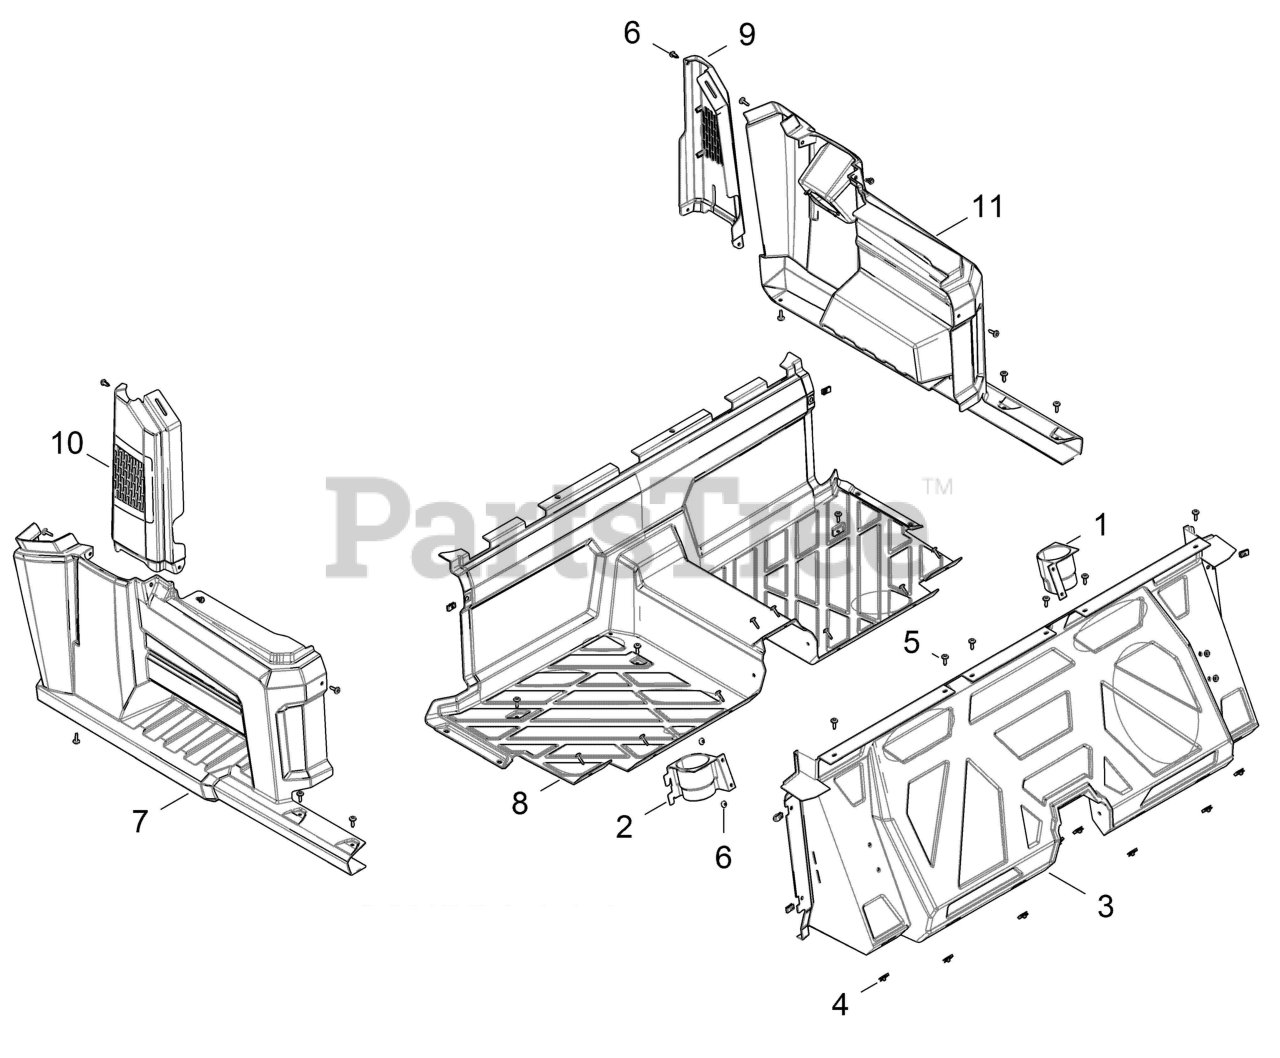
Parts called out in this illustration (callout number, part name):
1	HOLDER, CUP, LH, BLACK
2	HOLDER, CUP, RH,BLK
3	FLOOR,PANEL,REAR,BLK
4	CLIP-U SPEED NUT
5	SCR-TXTH-M6X1.0X25 RIE
6	RIVET-TUFLOK,.315-.325X.787 (5
7	FENDER,REAR,W/ROCKER,CREW,RH
8	FLOOR,REAR,BLK
9	ASM-FENDER-REAR,UPPER,LH,BLK
10	ASM-FENDER-REAR,UPPER,RH,BLK
11	FENDER,REAR,W/ROCKER,CREW, LH
